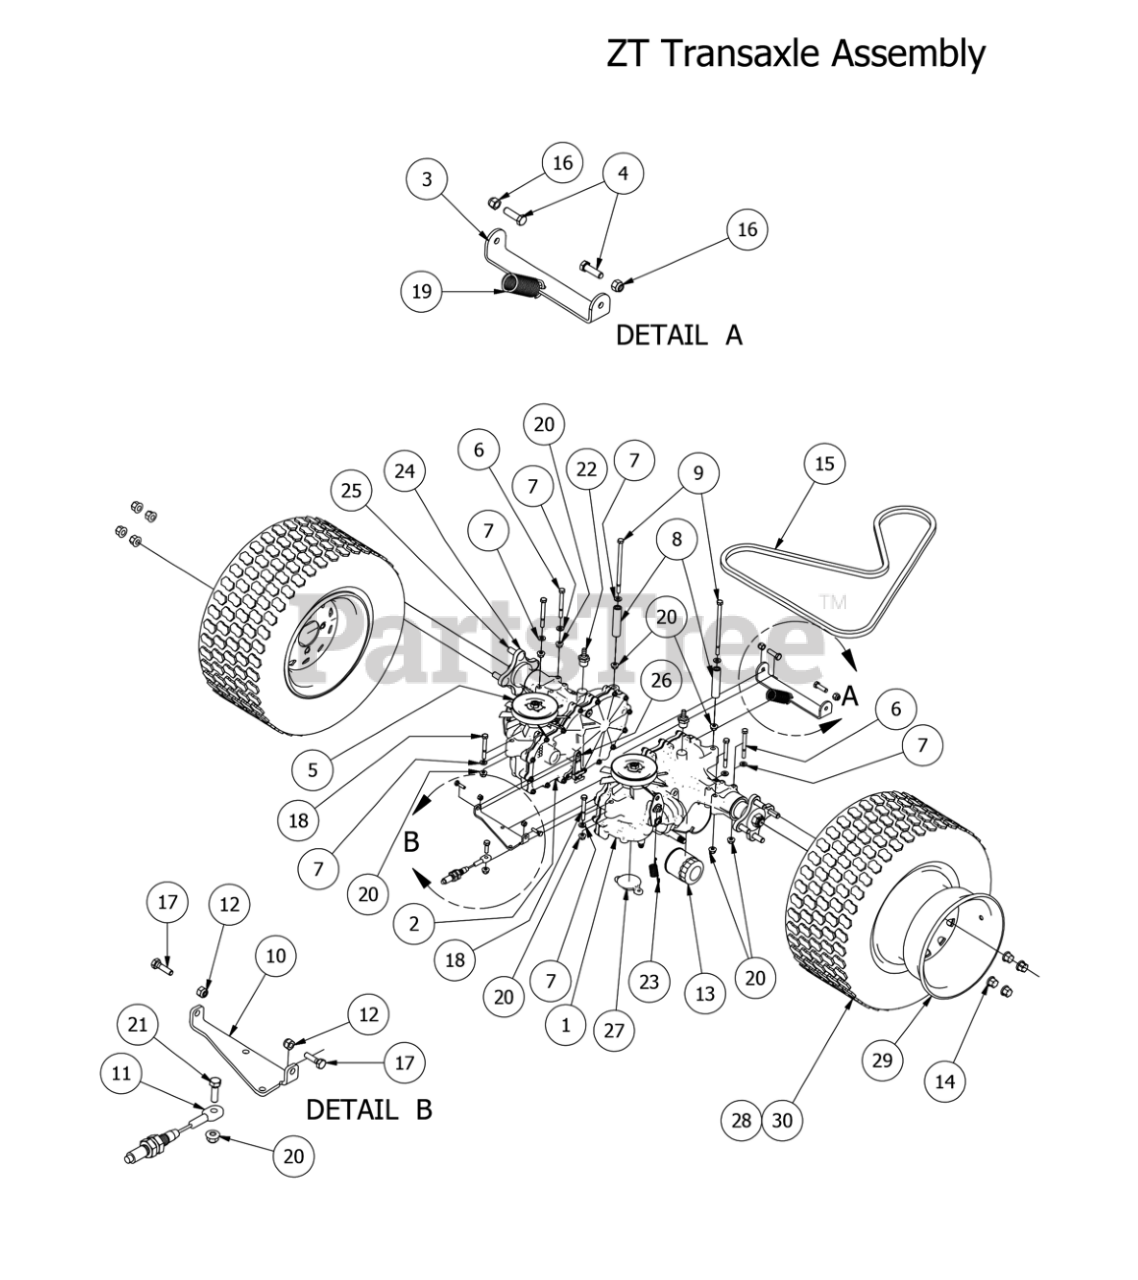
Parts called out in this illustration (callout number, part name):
1	Left ZT Transaxle
2	Right ZT Transaxle
3	Crossover Bar for ZT
4	3/8" x2" Hex Bolt
5	Fan/Pulley Kit
6	5/16" x 3" Hex Bolt
7	5/16" Flat Washer
8	3 1/4" Spacer
9	5/16" x 6" Bolt
10	ZT Crossover Brake Bracket
11	Brake Cable Stand On
12	1/4" Nylock Nut
13	Transaxle Filter
14	Acorn Lug Nut
16	3/8 Nylock Nut
17	1/4-20 x 1 GR 5 hex bolt zinc
18	5/16" x 2 1/2" Bolt
20	5/16" Nylon Flange Nut
21	5/16" x 1" Bolt
22	45 degree fitting
23	Transaxle Spring
24	ZT Transaxle Hub
25	Transaxle Wheel Studs
26	Transaxle Brake Lever
27	ZT Transaxle Charge Plate/With O'Ring
28	2014 ZT Assembly 22x11-10(Wheel and Tire)
29	2014 ZT Wheel Only 22x11-10
30	2014 ZT Tire Only 22x11-10
